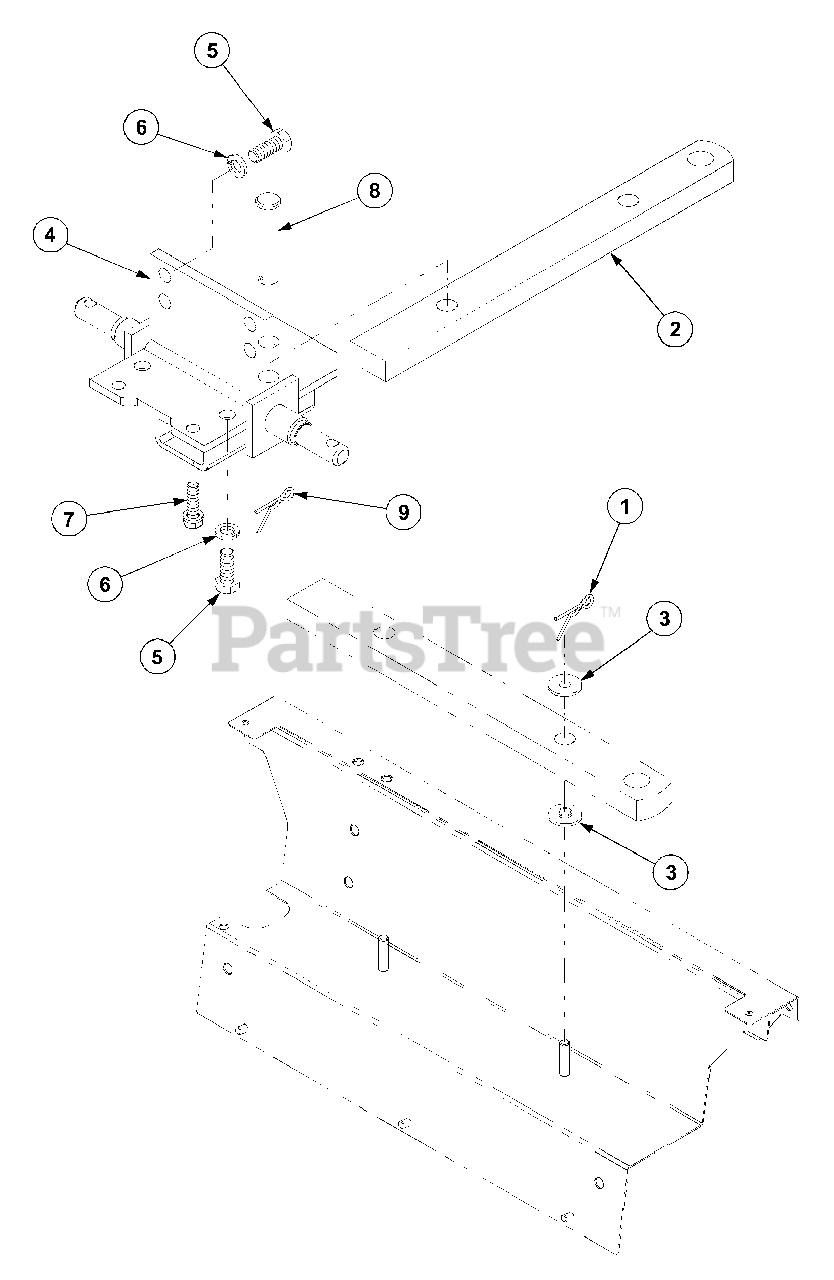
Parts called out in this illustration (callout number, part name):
4	Bracket,Drawbar
6	Washer,Spring
7	Bolt,w/Washer
